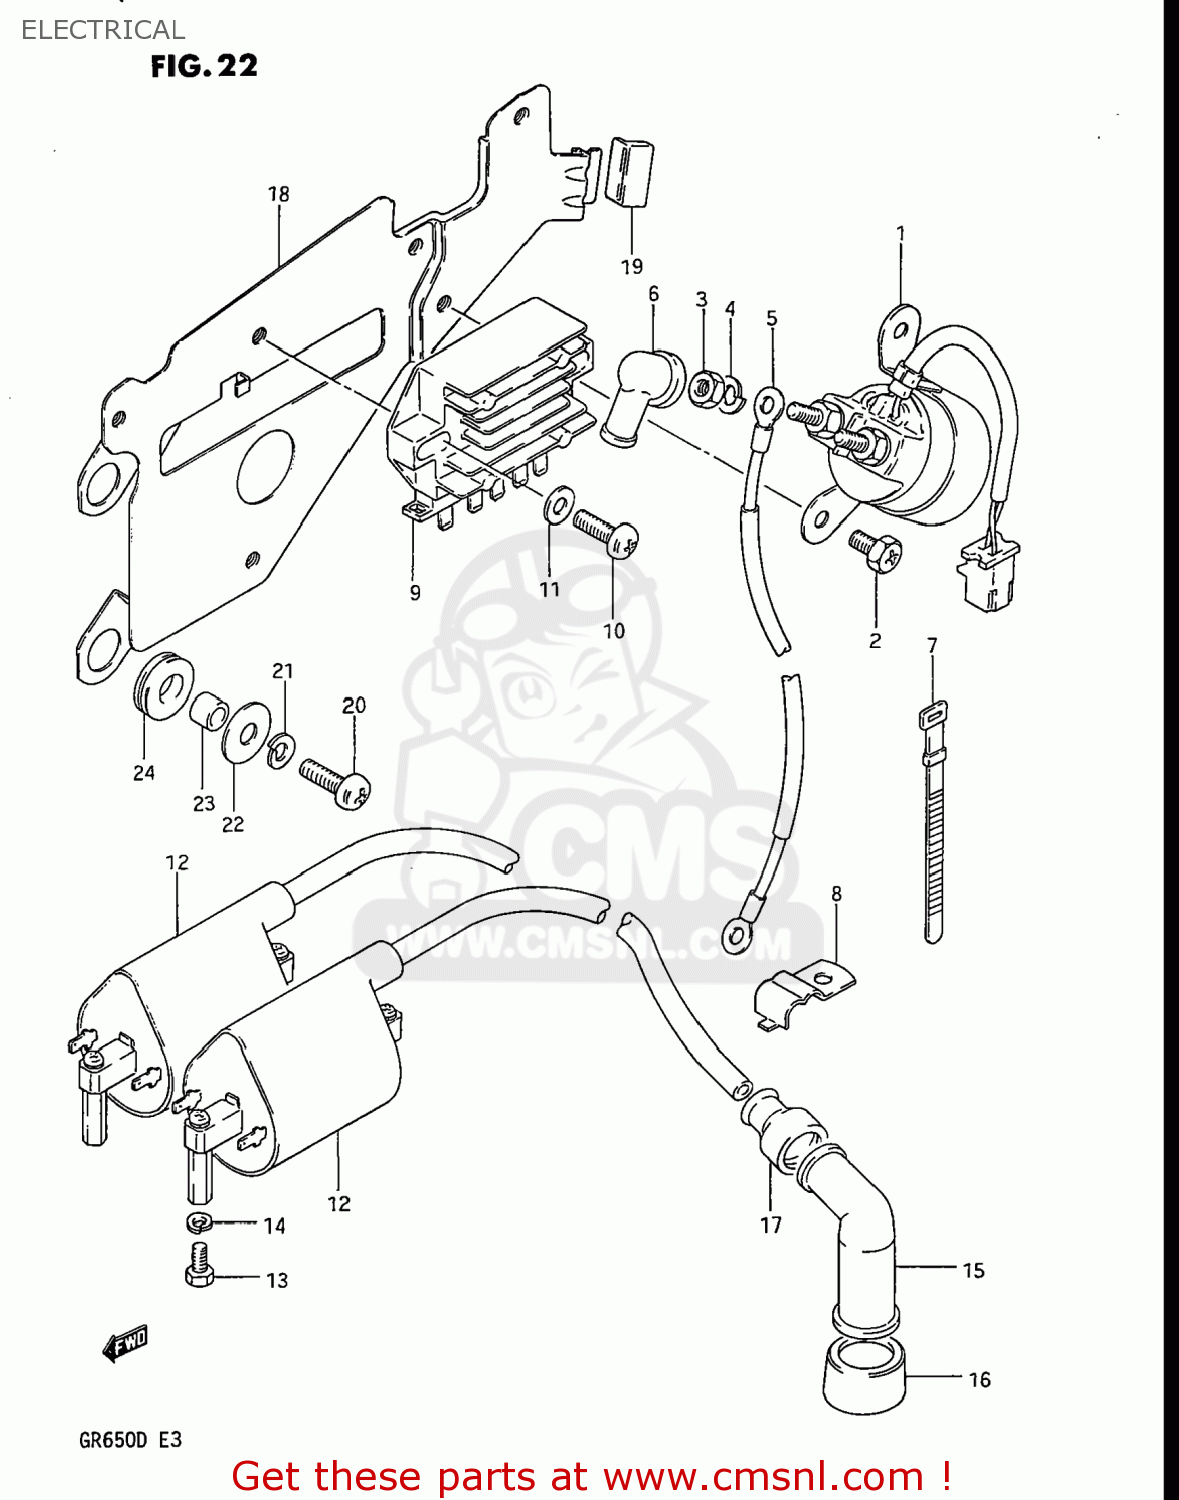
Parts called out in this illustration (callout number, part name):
1	RELAY ASSEMBLY,STARTING MOTOR
2	SCREW(6X10)
3	NUT 6MM
4	LOCK WASHER
5	CABLE,STARTING MOTOR
6	CAP,STARTER MOTOR TERMINAL
7	CLAMP(L:80)
8	CLAMP
9	RECTIFIER ASSEMBLY
10	SCREW
11	WASHER
12	COIL ASSY,IGNITION
13	BOLT
14	LOCK WASHER
15	CAP ASSY,SPARK PLUG
16	SEAL,SPARK PLUG
17	SEAL,SPARK PLU
18	PLATE, PARTS HOLDER
19	CUSHION,FRAME COVER
20	SCREW
21	LOCK WASHER
22	WASHER
23	SPACER (6.3X9.1X6.7)
24	CUSHION
